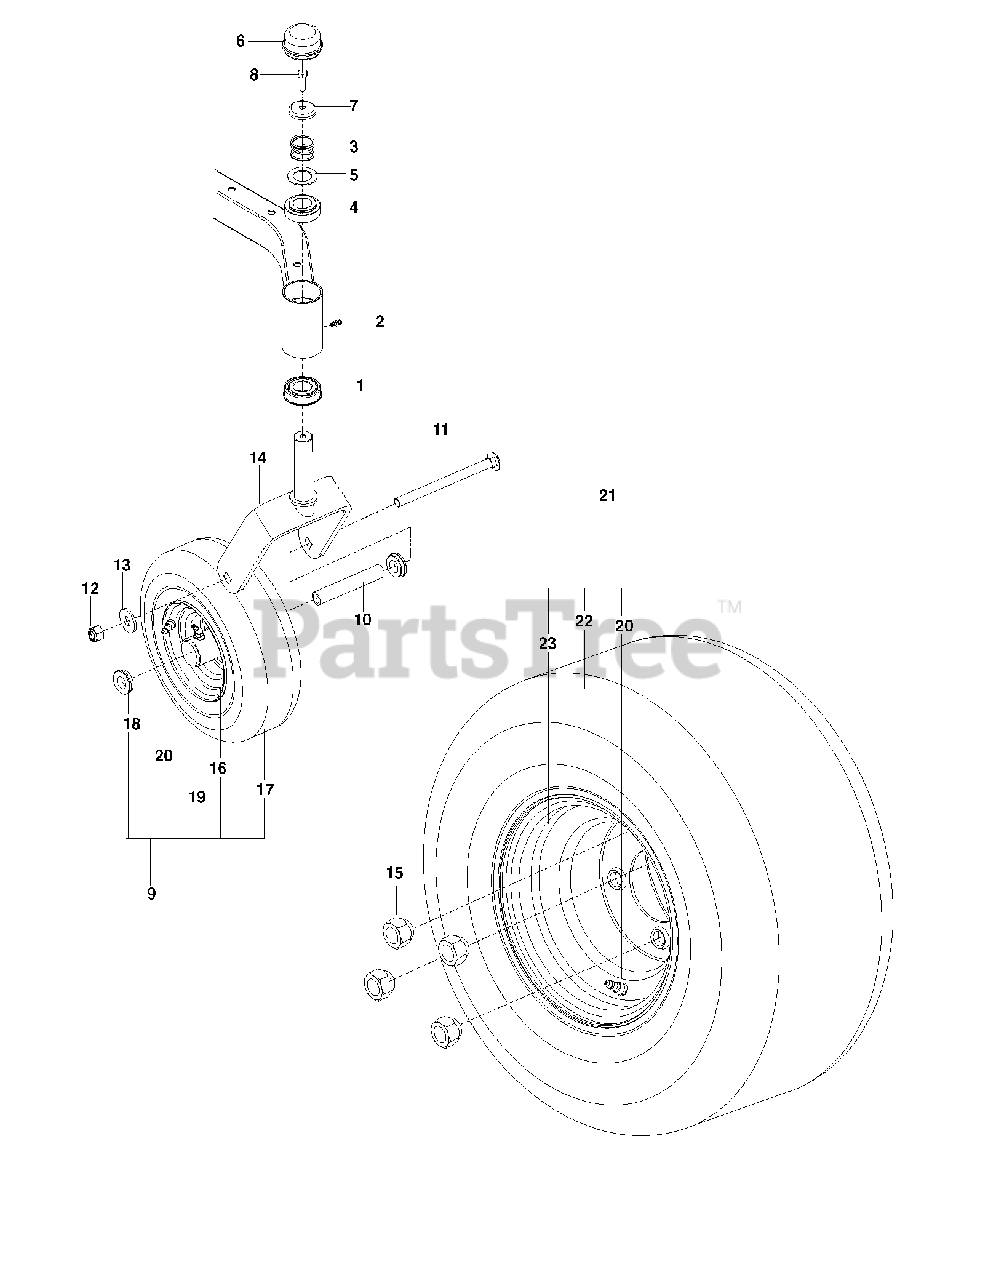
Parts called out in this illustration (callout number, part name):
1	BEARING FLANGED
2	ZERK, 3/16, DRIVE IN
3	SPRING, CASTER
4	BUSHING, CASTER
5	WASHER, 1.025 ID X 1.64
6	GREASE CAP
7	CASTER.PLUG
8	5/16-18X1 HHB G5W/NY
9	WHEEL ASSY, WIDE, RZ
10	SPACER, PIVOT
11	RHSNB 1/2-13 X 7.5
12	NUT 1/2-13 HEX CNTRLK GR 5 ZD
13	WASH USS FLAT 1/2
14	YOKE.CASTER.ORANGE
15	LUG NUT 1/2F
17	TIRE.11"X4"-5.4PLY.SMOOTH.KEND
18	BUSHING, WHEEL, 3/4"
19	ZERK
20	VALVE STEM TR-412
21	TIRE ASM, 20 X 8-8
22	TIRE 20 X 8, TURF
23	RIM.8X7.W/8".OFFSET.SILVER.ZTR
